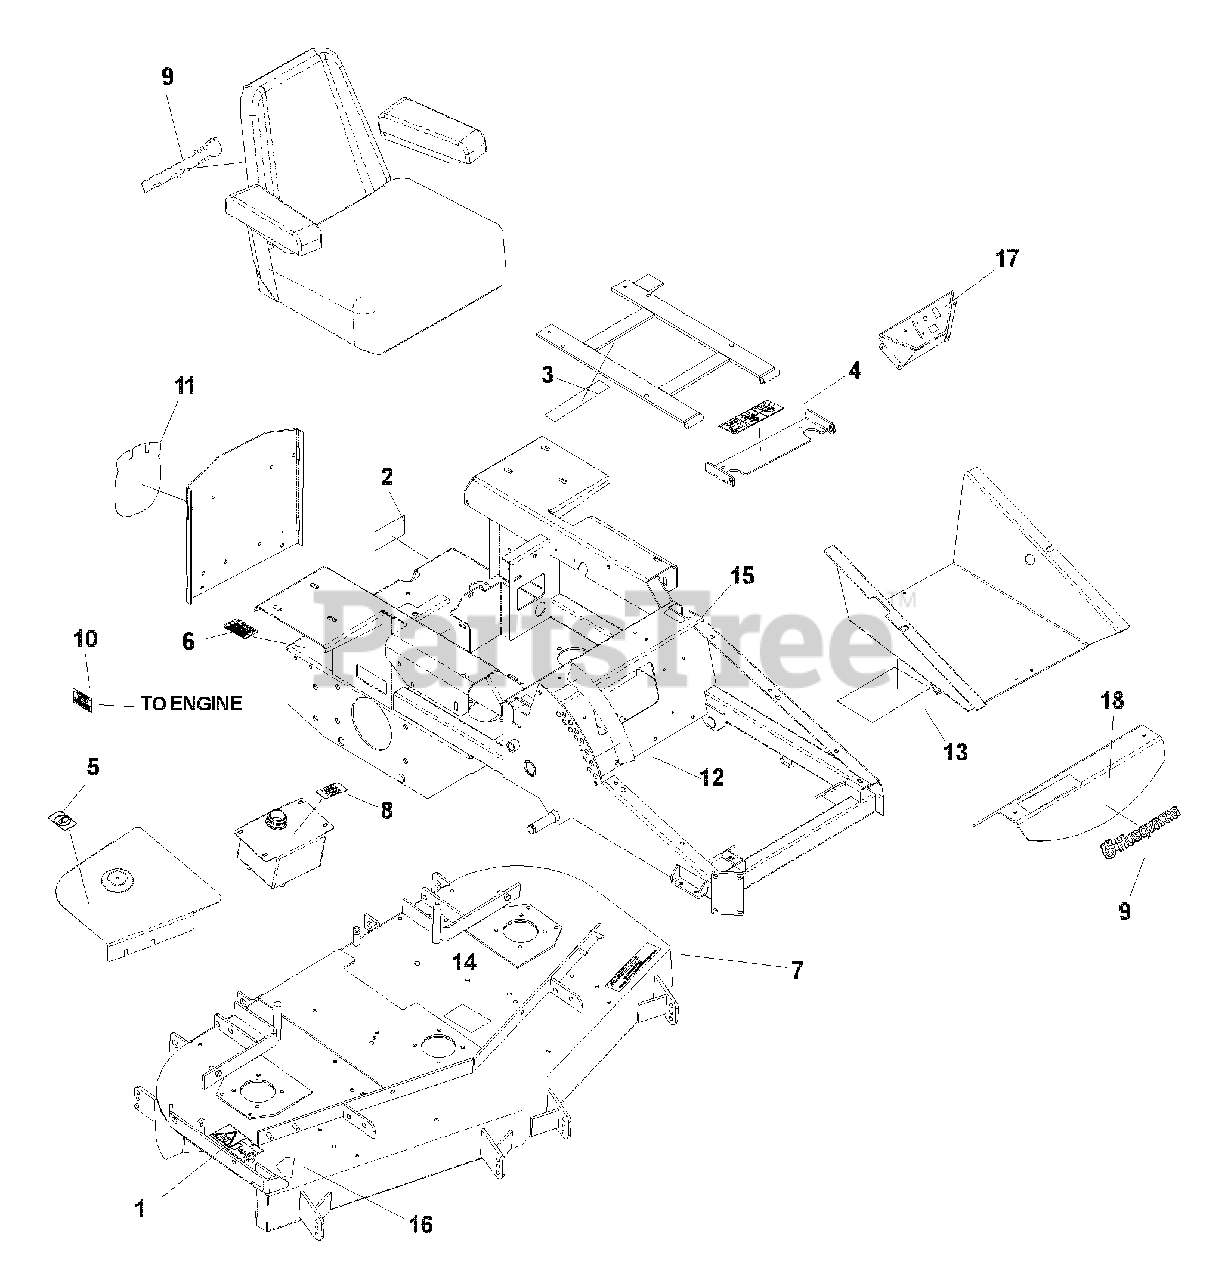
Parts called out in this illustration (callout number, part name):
1	DECAL, SEVERING
2	DANGER DECAL, BELT DRIVES
3	DECAL, BATTERY WARNING
4	DECAL, WARNING
5	DECAL, NO STEP
6	PROP. 65
7	DECAL, NASCAR
8	MOBIL DECAL
9	DECAL, HUSQVARNA
10	EXHAUST DECAL
11	DECAL, CROWN
12	DECAL, HEIGHT ADJ.
13	DECAL, SERVICE
14	DECAL, BELT ROUTING
15	DECAL, MOTION CONTROL
16	DECAL, DANGER
17	DECAL, CONSOLE
18	DECAL, iZ4817
18	DECAL, iZ6123
18	DECAL, iZ4821
18	DECAL, iZ5223
18	DECAL, iZ4217
